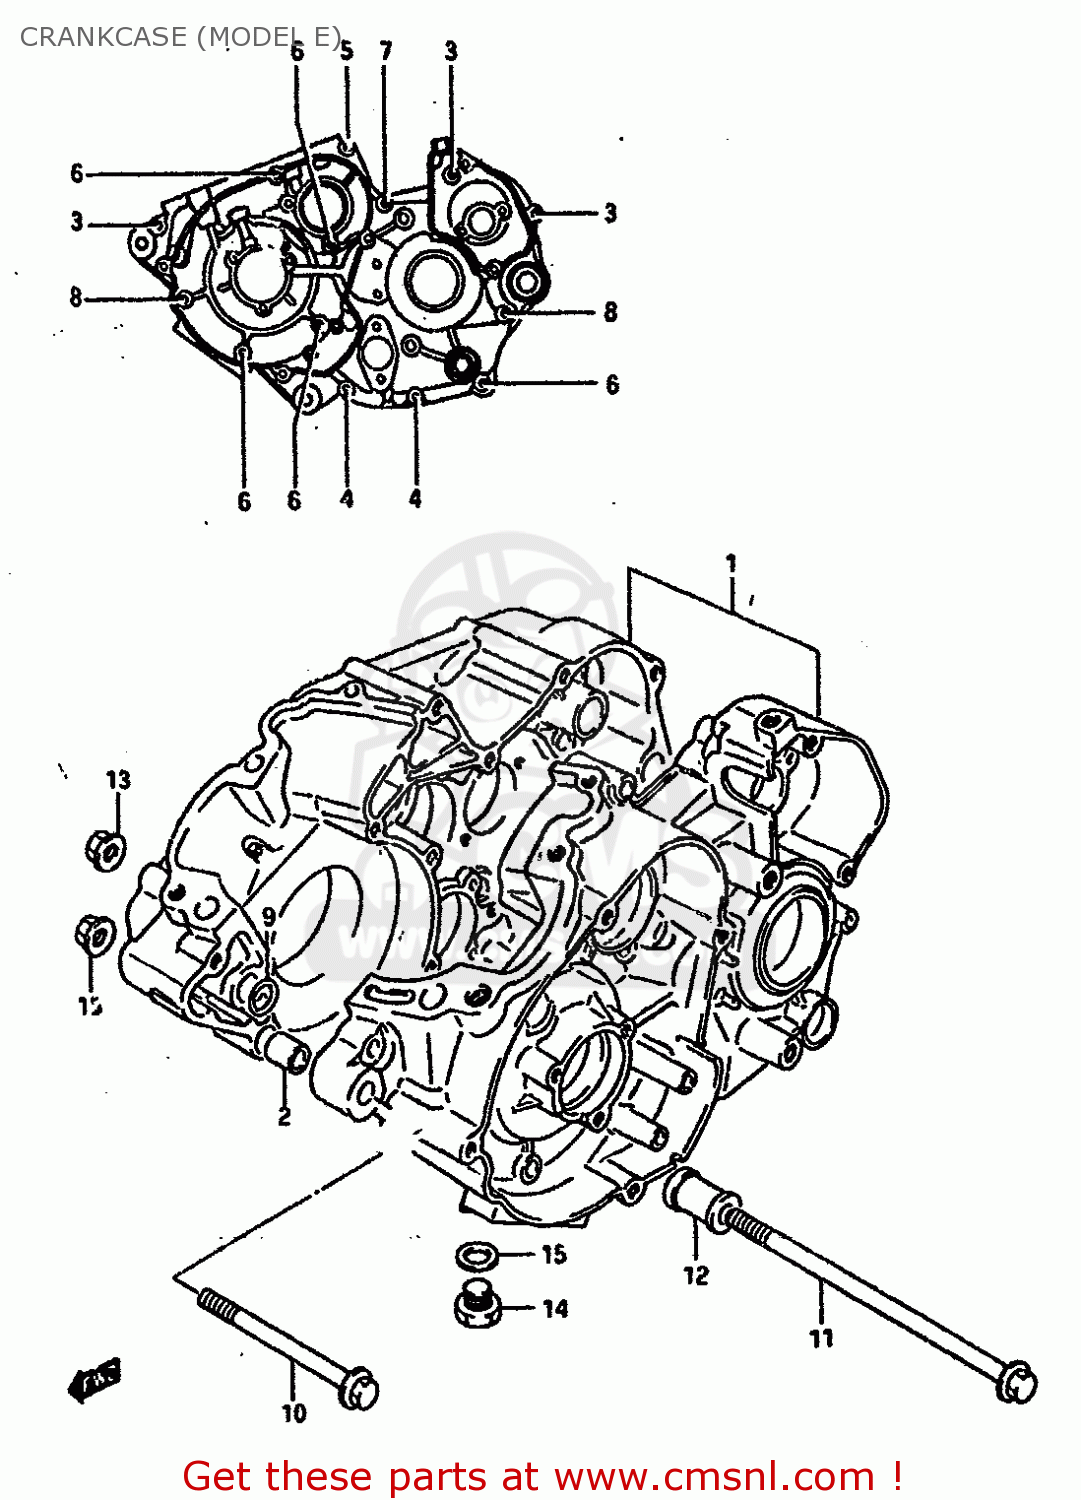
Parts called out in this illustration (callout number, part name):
1	CRANKCASE SET
2	PIN
3	SCREW
4	SCREW
5	SCREW
6	SCREW
7	SCREW (6*60)
8	SCREW
9	O RING(D:1.9,ID:13.8)
10	BOLT(8X100)
11	BOLT (8X200)
12	SPACER,ENGINE MOUNTING (L:32)
13	NUT
14	PLUG
15	GASKET(14X19.2X2) (NAS)
